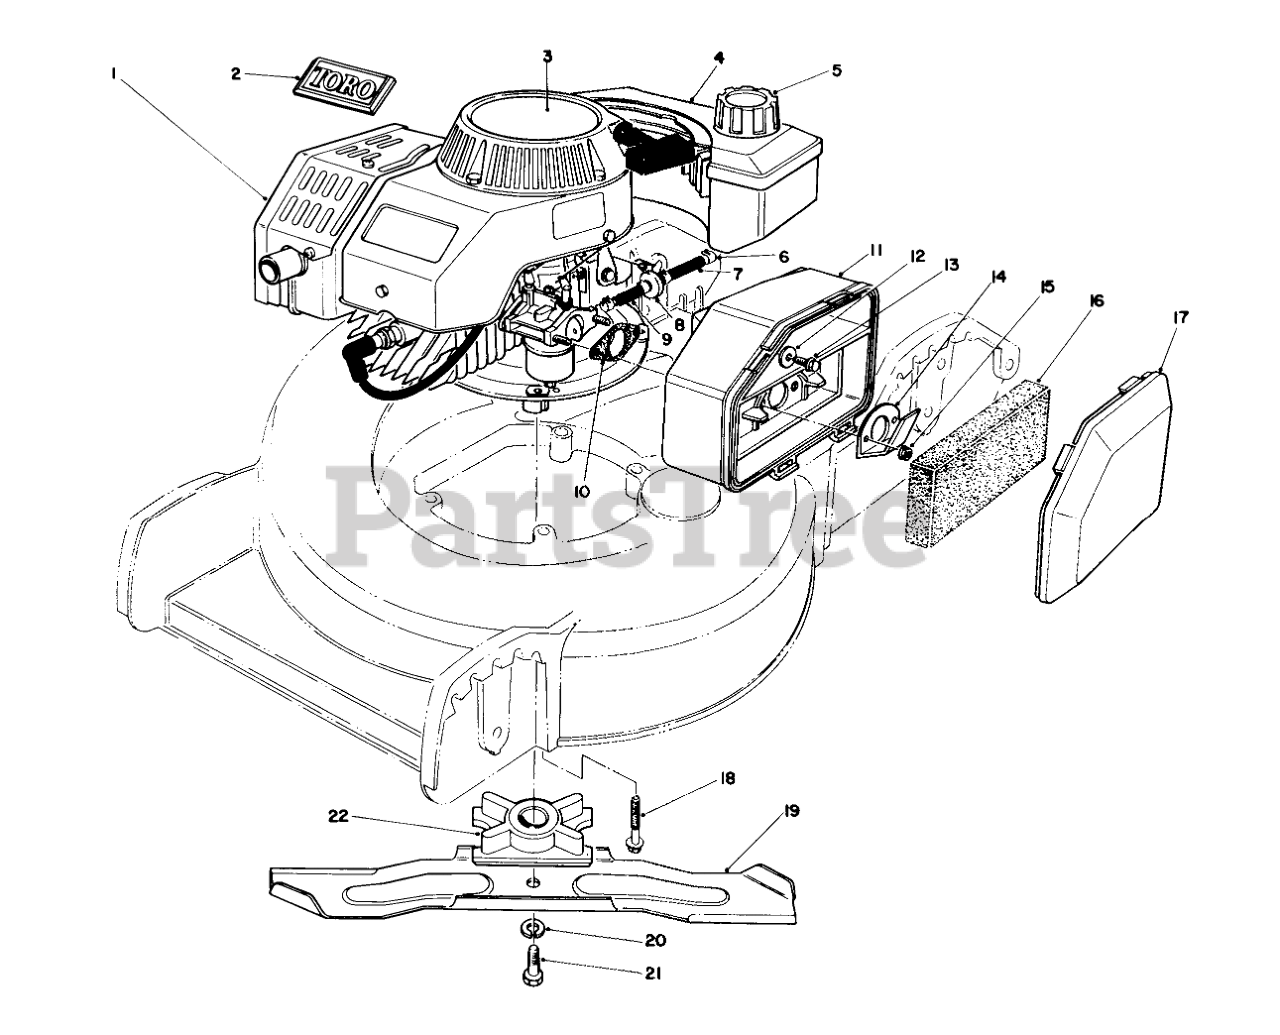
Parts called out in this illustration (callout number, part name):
1	Engine
2	TORO LOGO PLT
3	DECAL- 2 CYC RECOIL
4	Gas Tank Assembly
5	GAS CAP ASM
6	CLAMP-FUEL LINE
7	HOSE-FUEL
8	FILTER-FUEL
9	HOSE-FUEL
10	GASKET-AIR CLEANER
11	AIR CLEANER
12	WASHER-FLAT
13	SCREW-HH
14	SPIT BACK DEFLECTOR
15	NUT-LOCK
16	FILTER
17	AIR CLEANER COVER
18	SCREW-HHF
19	Blade
20	WASHER-LOCK
21	SCREW-HH
22	BLADE RETAINER
